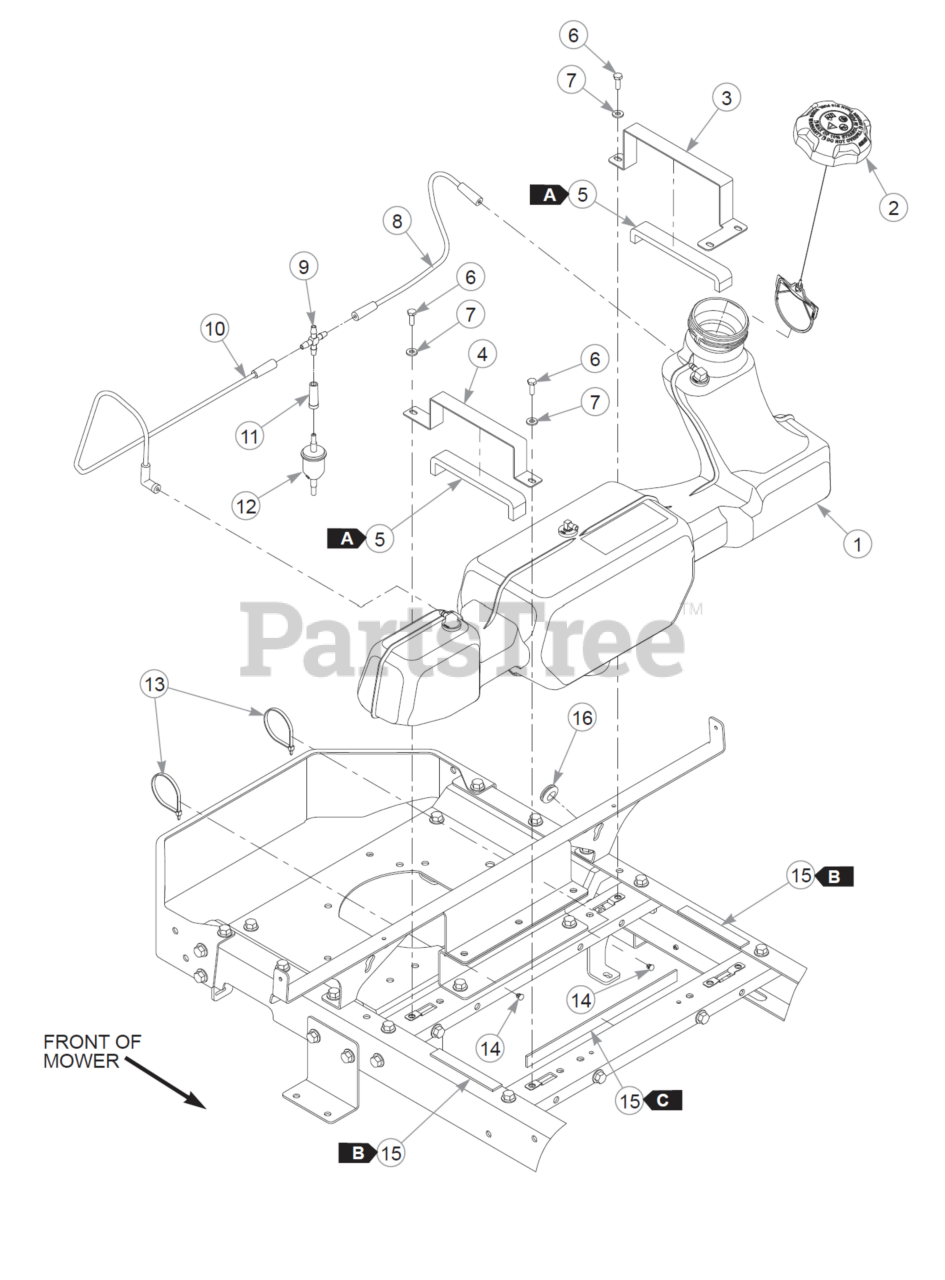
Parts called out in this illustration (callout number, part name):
1	FUEL TANK
2	CAP, 3.5" RATCHETING GAS
3	TANK MNT LEFT
4	TANK MNT RIGHT
5	SEAL 3/8x3/4 SOLD BY FT
6	CS .250-20X0.75 HX G5 ZN
7	FW 0.281SAE
8	VAPOR LINE, 3/16 FORMED
9	1/4" HOSE BARB CROSS
10	VAPOR LINE, 3/16 FORMED
11	BOOT, 3/16" TO 1/4" BARB
12	VAPOR SYSTEM FILTER
13	WIRE TIE, SMALL/SHORT
14	MOUNT, PUSH BUTTON
15	WEATHERSTRIP .12X.75
16	GM .63 x1.13 x.88 x .13
